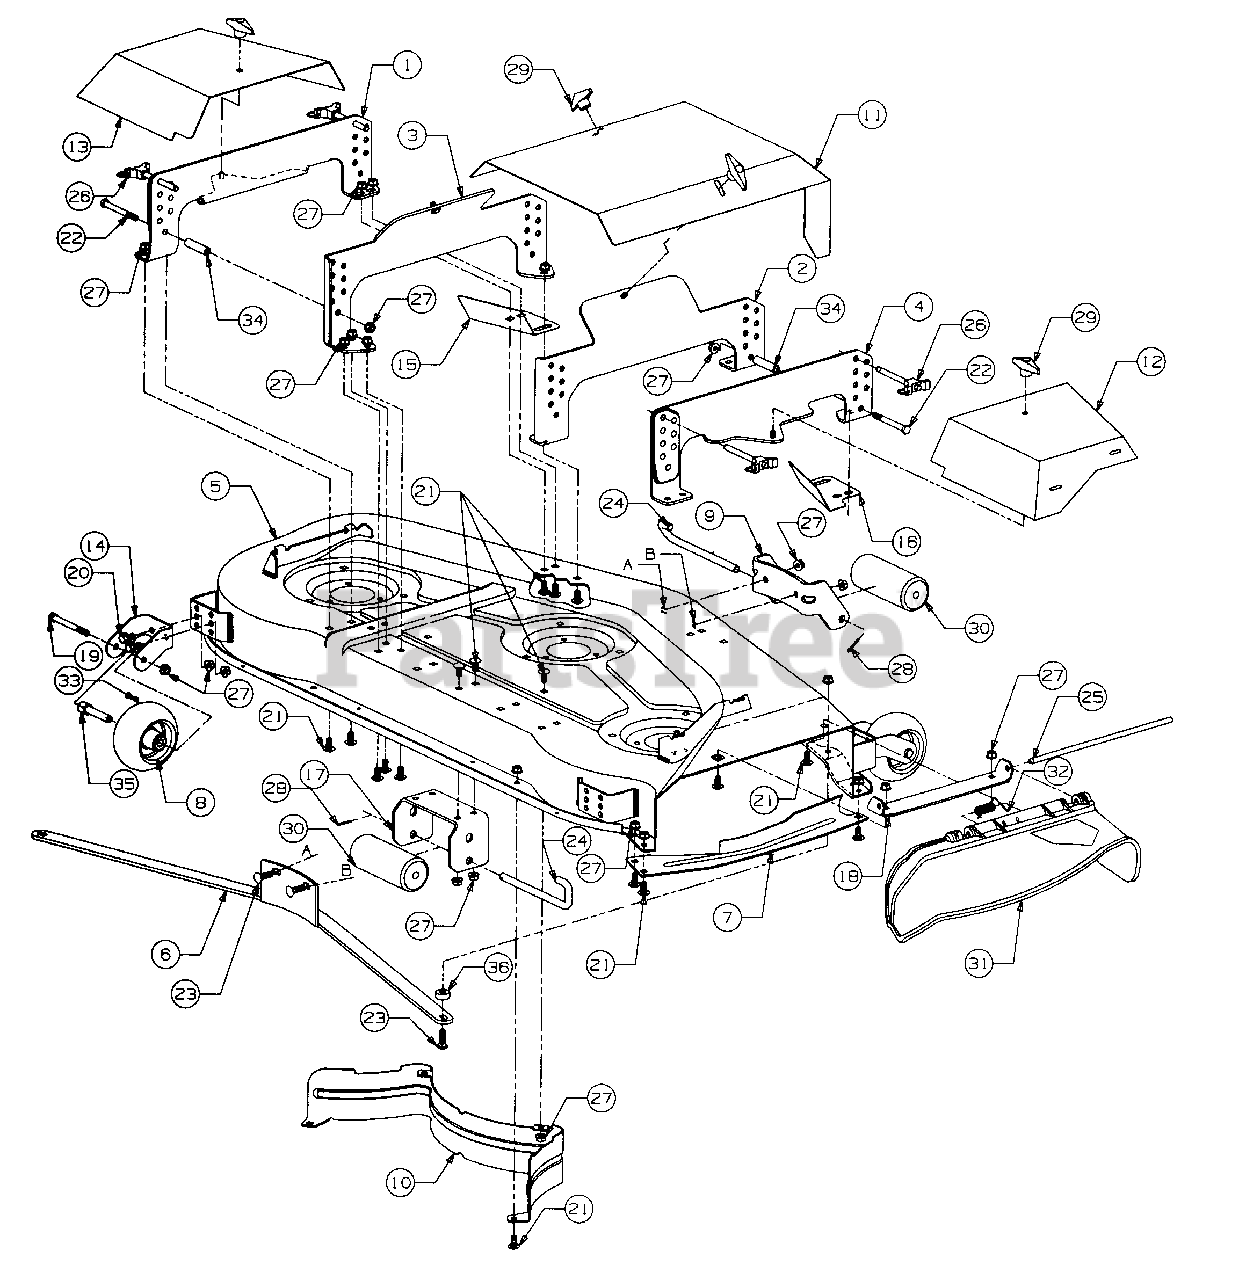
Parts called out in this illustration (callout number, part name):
4	Hanger, RH Outer
5	Housing Assy w/Graphics, 54" Mower
8	Wheel, Deck, 5" Dia w/Fitting
16	Plate, RH Filler
19	Screw, Hex Cap, 3/8-16 X 3.75 Lg
20	Screw, Hex Wash Sf Tap, 3/8-16 X .75 Lg
21	Bolt Sht Nk Carriage, 3/8-16 X .75 Lg GR5
22	Screw, Hex Cap, 3/8-16 X 3.25 Lg GR5
23	Bolt, Carriage, 3/8-16 X 1.25 Lg GR5
24	Pin, Roller, 1/2 Dia X 7.31 Lg
25	Pin, Hinge, .375 Dia X 12.55
26	Pin, Quick Release, 3/8 Dia
27	Nut, Hex Flanged Lock, 3/8-16
28	Pin, Cotter, 1/8 Dia X 1.0 Lg
29	Knob, Wing Nut
31	Deflector, Chute
32	Spring, Torsion
33	Fitting, Lube, 3/16 Drive
34	Spacer, Deck Hanger
35	Spacer, Deck Wheel
36	Spacer, Front Bar
